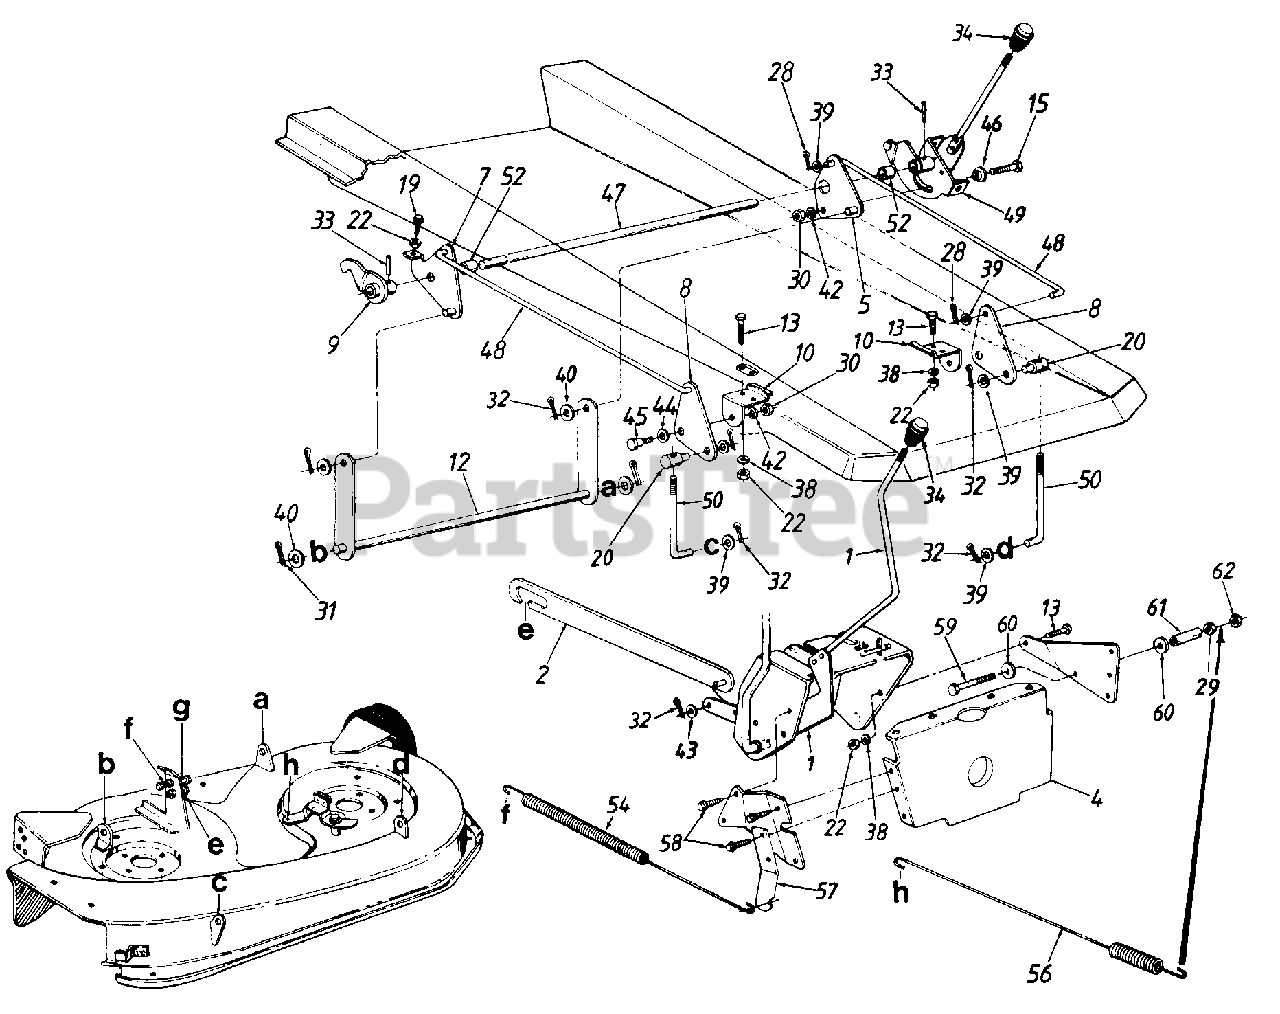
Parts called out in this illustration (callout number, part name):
7	Deck Lift Brkt. Ass'y.
8	Deck Lift Bracket
9	Deck Lift Float Brkt Ass'y.
10	Deck Lift Pivot Brkt.
12	Stabilizer Shaft Ass'y.
13	Hex Bolt 5/16-18 x .75" Lg.
15	Hex Bolt 3/8-16 x 1" Lg.
19	Hex Wash.-Tap Scr. 5/16-18 x 1.25" Lg.
20	Ferrule
22	Hex Nut 5/16-18 Thd.
28	Cotter Pin 3/32" Dia.
29	Hex Nut 1/4-20 Thd.
30	Hex Nut 3/8-16 Thd.
31	Internal Cot. Pin 1/2" Dia.
32	Int. Cot. Pins 318" Dia.
33	Spring Pin Spir. 1/4" Dia.
34	Knob
38	L-Wash 5/16" I.D.
39	Fl-Wash. .385 I.D. x .62
40	Fl-Wash. .635 I.D. x 1.12
42	L-Wash. 3/8" I.D.
43	Fl-Wash. .385 I.D. x .87 O.D.
44	Spring Washer .530 I.D.
45	Shld. Bolt .500" Dia. x .215"
46	Shld. Spacer .625" I.D.
47	Rear Hgt. Adj. Shaft
50	J-Bolt 5.4" Lg.
52	Spacer .885 I.D.
54	Ext. Spring 22.05" Lg.
56	Ext. Spring 15-5/8" Lg. (32" Deck)
57	Spring Anchor
58	Hex Wash. Hd. AB-Tap Scr. 1/4 x.62" Lg.
59	Hex Bolt 1/4-20 x 2.5" Lg.
60	Fl-Wash. .25" I.D. x .93" O.D.
61	Spacer.255" I.D.
62	Hex L-Nut 1/4-20 Thd.
